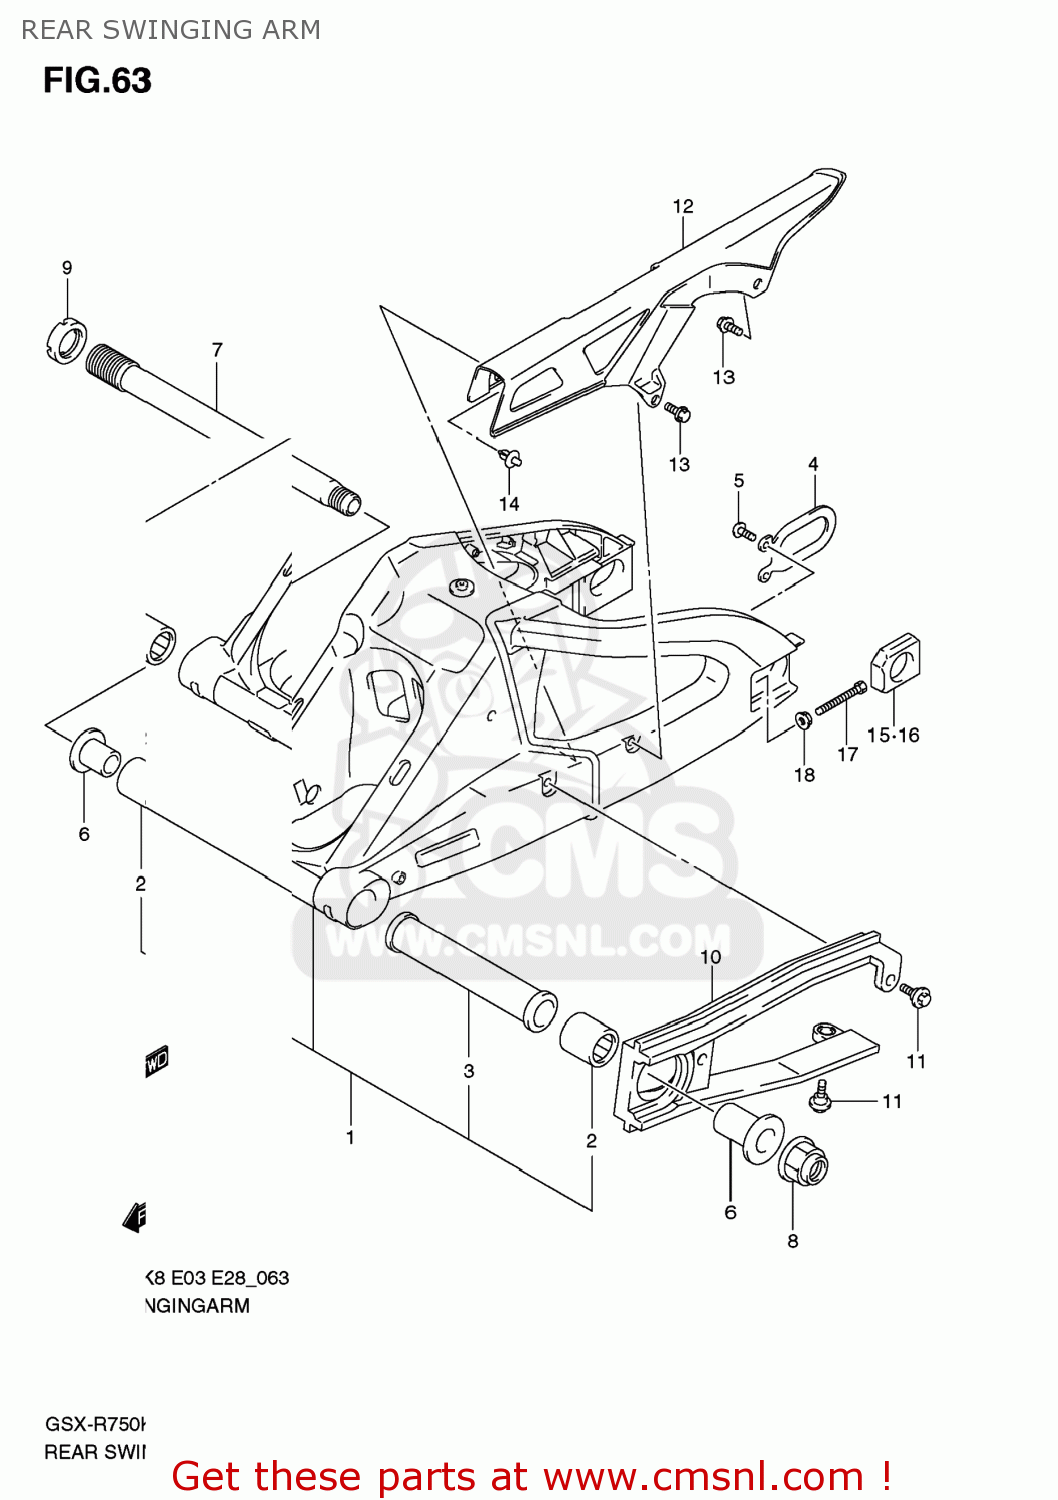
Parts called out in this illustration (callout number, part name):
1	SWINGINGARM ASSY,RR
2	BEARING(27X35X35)
3	SPACER,RR SWG PVT CTR
4	PLATE,RR SWING ARM BRKT
5	SCREW(6X16)
6	SPACER,RR SWGARM PIVOT BEARING
7	SHAFT,RR SWINGINGARM PIVOT
8	NUT
9	NUT,REAR SWGAR
10	BUFFER,CHAIN TOUCH DEFENSE
11	BOLT(6X17.8)
12	CASE,CHAIN
13	BOLT(6X14)
14	CLIP(BLACK)
15	ADJUSTER,CHAIN
16	ADJUSTER,CHAIN
17	BOLT(8X50)
18	NUT
